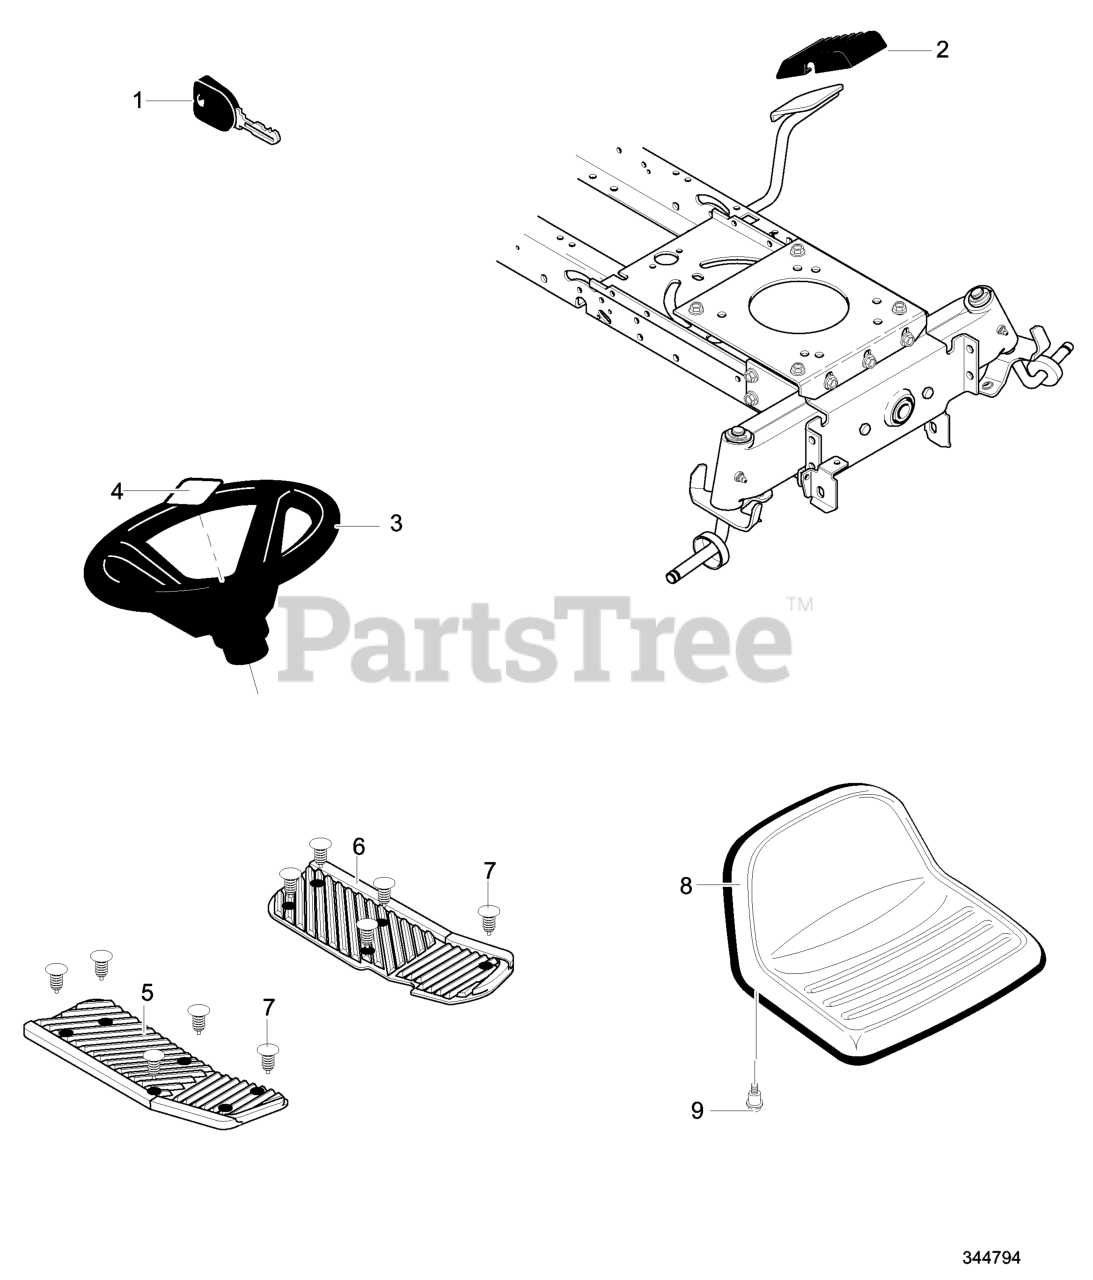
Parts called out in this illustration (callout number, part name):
1	IGNITION KEY
2	PAD, CLUTCH/BRAKE
3	STEERING WHEEL
4	INSERT, 4-SPOKE
5	FOOTREST PAD RH
6	FOOTREST PAD LH
7	RATCHET FASTENER
9	SHOULDER BOLT 5/16-18
